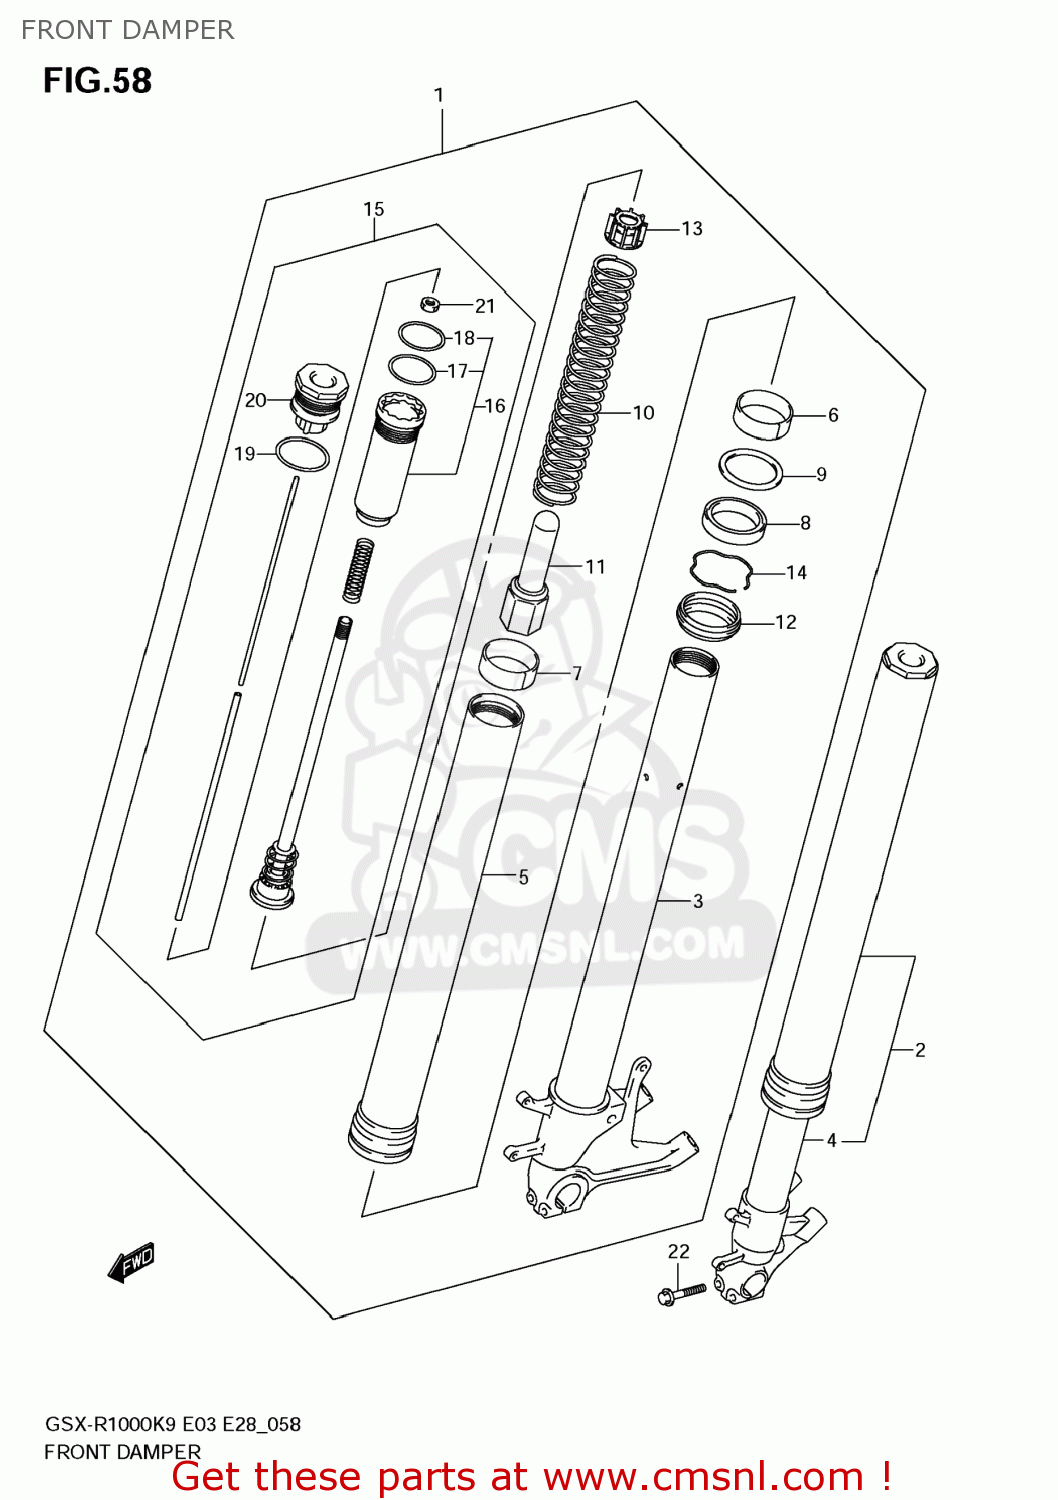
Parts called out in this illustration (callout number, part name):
1	DAMPER ASSY,FR FORK,R
2	DAMPER ASSY,FR FORK,L
3	TUBE,INNER,R
4	TUBE,INNER,L
5	TUBE,OUTER
6	BUSH,GUIDE
7	BUSH,SLIDE
8	SEAL,OIL
9	SPACER,SEAL
10	SPRING
11	COLLAR,SPRING
12	SEAL,DUST
13	COLLAR,SPRING
14	CIRCLIP,FORK OIL SEAL
15	ROD,PISTON
16	CASE,ROD GUIDE
17	RING,PISTON
18	O RING
19	O RING
20	BOLT
21	NUT
22	BOLT
